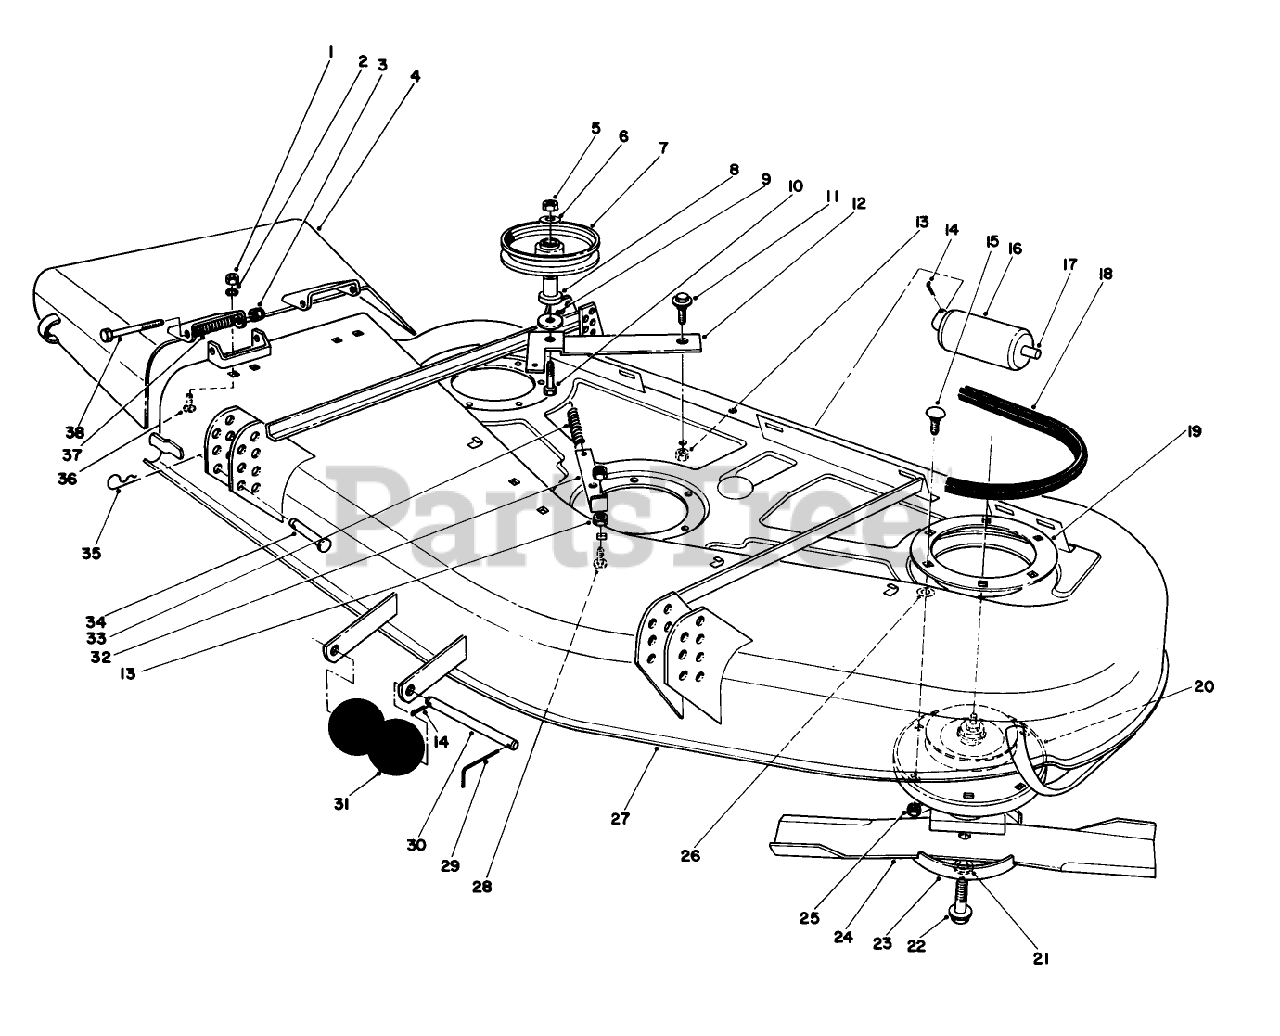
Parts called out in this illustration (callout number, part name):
1	NUT-HEX
2	SCREW-HH
3	NUT-HEX
5	NUT-LOCK, SIDE
7	PULLEY-IDLER
8	BUSHING-PULLEY
9	WASHER-FLAT
10	SCREW-HH
11	SCREW-SHOULDER
13	NUT-LOCK, NI
14	PIN-COTTER
15	SCREW-CARR
16	ROLLER-DECK
17	SHAFT-ROLLER, REAR
18	V-BELT, DECK
21	WASHER-LOCK
22	SCREW-BLADE
25	NUT-HF
26	WASHER-FLAT
28	SCREW-CARR
29	PIN-SPECIAL
30	SHAFT-ROLLER
31	ROLLER
33	SPRING-EXTENSION, DECK
34	PIN-CLEVIS
35	PIN-HAIR
36	SCREW-CARR
37	SPRING
38	SCREW-HH
